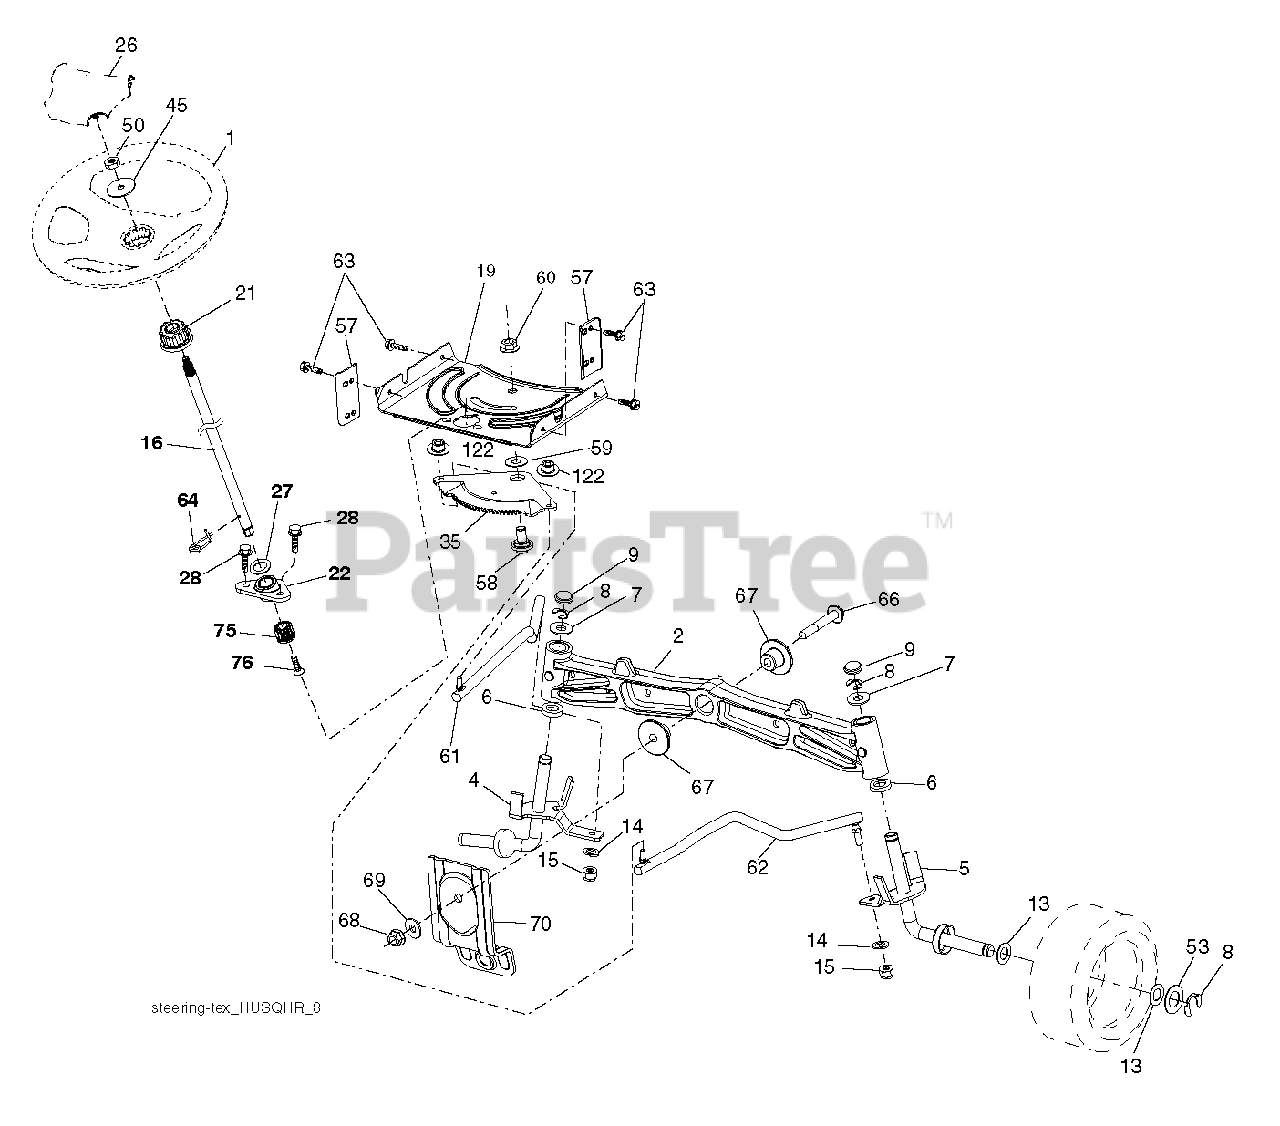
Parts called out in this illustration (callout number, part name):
1	WHEEL.STEER.HUSQ.SR.498.OVMLD
2	AXLE.CAST.IRON
4	SPINDLE.WELDED.LH.15"TEX
5	SPINDLE.WELDED.RH.15"T
6	THRUST WASHER
9	CAP.SPINDLE.BLACK
14	SLW 3/8 STD
15	NUT CROWNLOCK 3/8-24
16	SHAFT.STEER.2HIGH.SPLND.PLATED
19	PLATE.STEER.DDL.NLT/NG
21	ADAPTER.WHEEL.STEER.SPLND.ALUM
22	BEARING.SHAFT.STEER.LOWER.625
26	INSERT.CAP.WHL.STRG.HUSQ.PREM
28	SCREW, 3/8-16X3/4
35	GEAR.SECTOR.PLATE.DDL.
45	WASHER 9/16"ID, 2 3/8"OD
50	NUT LOCK FLG 3/8-16 UNC
53	WASHER.HARDENED
57	BRACKET.UPSTOP.TEX
58	BOLT.SHOULDER.SECTOR.P
59	WASHER.THURST.SECTOR.S
60	NUT FLANGE LOCK 5/8-11
61	DRAGLINK.LH.BALLSTUD.D
62	DRAGLINK.RH.BALLSTUD.D
63	SCREW
64	RETAINER.CLIP.SPRING.S
66	BOLT HEX FGHD 7/16-14 X 3 SERR
67	BUSHING.PM.FRONT AXLE
68	NUT.LOCK.FLANGE.7/16
69	WASHER.1.5X.505X.118
70	BRACKET.FRT.DECK.SUSP.RR.MT431
75	PINION.ZINC PLATED
76	SCREW HEAD SOCKET LRVB
122	CAP.GEAR.SECTOR.TEX
